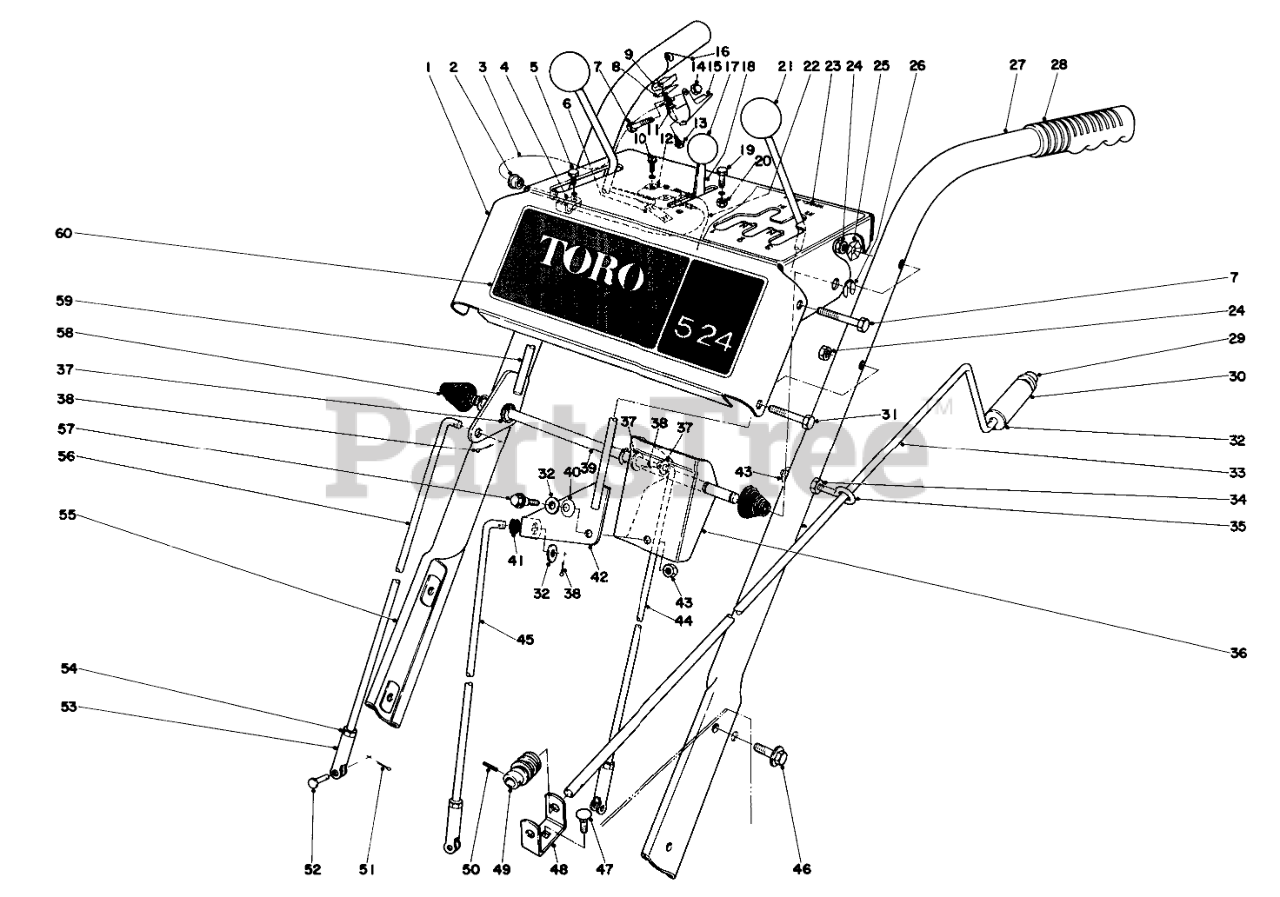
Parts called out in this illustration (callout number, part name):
1	Escutcheon Plate
2	Snap Bushing
3	Wire Ass-y.
4	PLASTIC CLIP
5	SCREW-HWHTF
6	NUT-SPEED
7	SCREW-HH
8	INTERLOCK CONTACT
9	Insulator
10	SCREW-HEAD, PAN
11	WASHER INSULATOR
12	MICRO SWITCH
13	Screw
14	NUT-CAP
15	Safety Lever
16	INTERLOCK SPRING
17	CONTROL KNOB
18	THROTTLE CONTROL
19	SCREW-HWH
20	Nut
22	Wire Ass-y
23	Decal Instruction
24	NUT-LOCK, CONE
25	Washer
26	RING-CLIP
27	Handle Left
28	Grip Handle
29	RETAINER-PUSH ON
30	CHUTE CONTROL GRIP
31	SCREW-HH
32	WASHER-FLAT
33	CHUTE CONTROL ROD
34	Nut
35	Eye Bolt
36	SHIFT BRACKET
37	WASHER-FLAT
38	PIN-COTTER
39	PIVOT ROD
40	7/16 SPRING WASHER
41	GROMMET-RUBBER
42	SHIFT LEVER WA
43	NUT-LOCK, CONE
44	TRACTION CONTROL ROD
45	SPEED SELECTOR ROD
46	SCREW-HHF
47	BOLT-CARR
48	WORM BRACKET
49	GEAR-WORM, CHUTE
50	PIN-SPRING
51	PIN-COTTER
52	PIN-CLEVIS
53	Clevis
54	NUT-HJ
55	Handle Right
56	Auger Control Rod
57	SHOULDER SCREW
58	CONICAL SPRING
59	LEVER WA
60	Decal, Escutcheon (Used on Model 31624 only)
